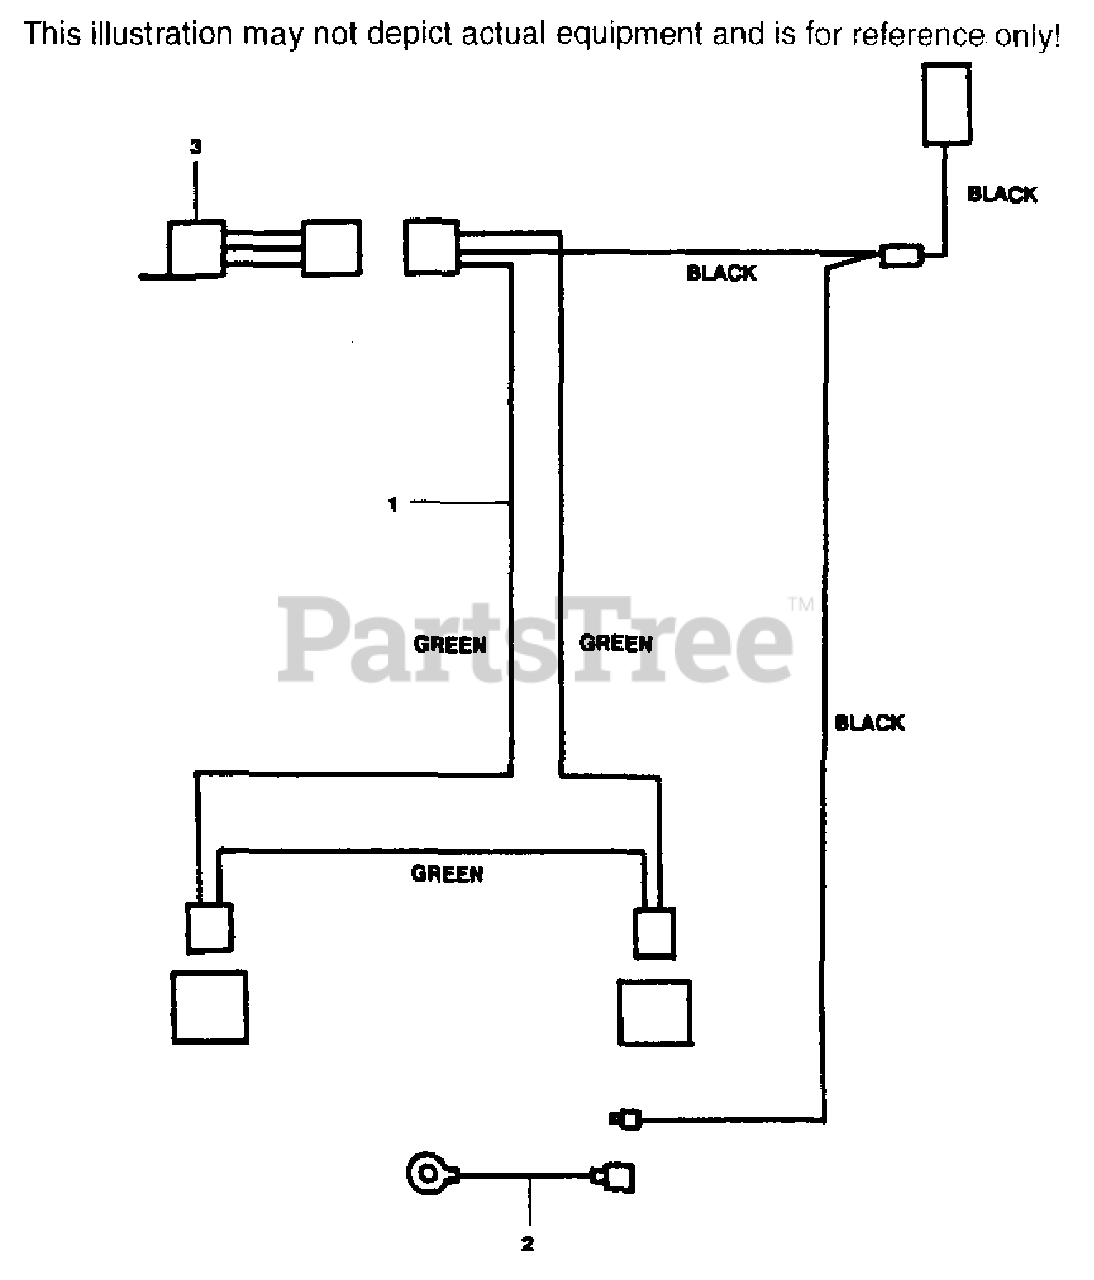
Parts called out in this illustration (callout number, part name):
1	WIRING HARNESS
2	ADAPTER FOR B & S
3	IGNITION INTERLOCK
